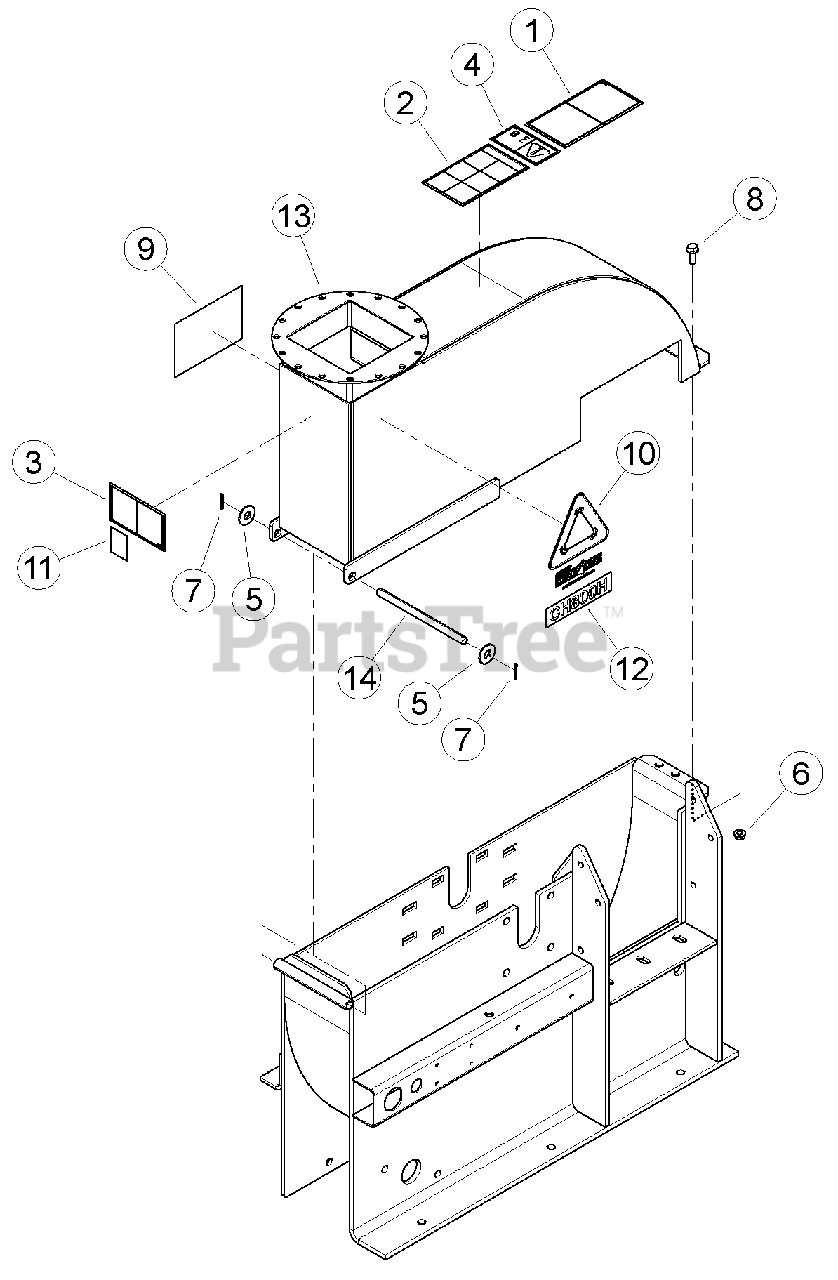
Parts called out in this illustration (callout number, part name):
1	DECAL, KNIFE ACCESS ISO
2	DECAL, OPERATING INSTRUCTIONS ISO
3	DECAL, DISCHARGE ISO
4	DECAL, MAINTENANCE ISO
5	WASHER, 1/2 FLAT
6	NUT, 3/8-16 SERRATED FLANGE
7	PIN, 1/8 X 1.00 ZP COTTER
8	BOLT, 3/8-16 X 1 SERRATED FLANGE GR5
9	DECAL, FLOW RATE HYDRAULIC
10	DECAL, CHIP IT
11	DECAL, ECHO BEARCAT QR CODE
12	DECAL, MODEL CH800H
13	WELDMENT, TOP CHIPPER HOUSING
14	SHAFT, CHIPPER TOP PIVOT
